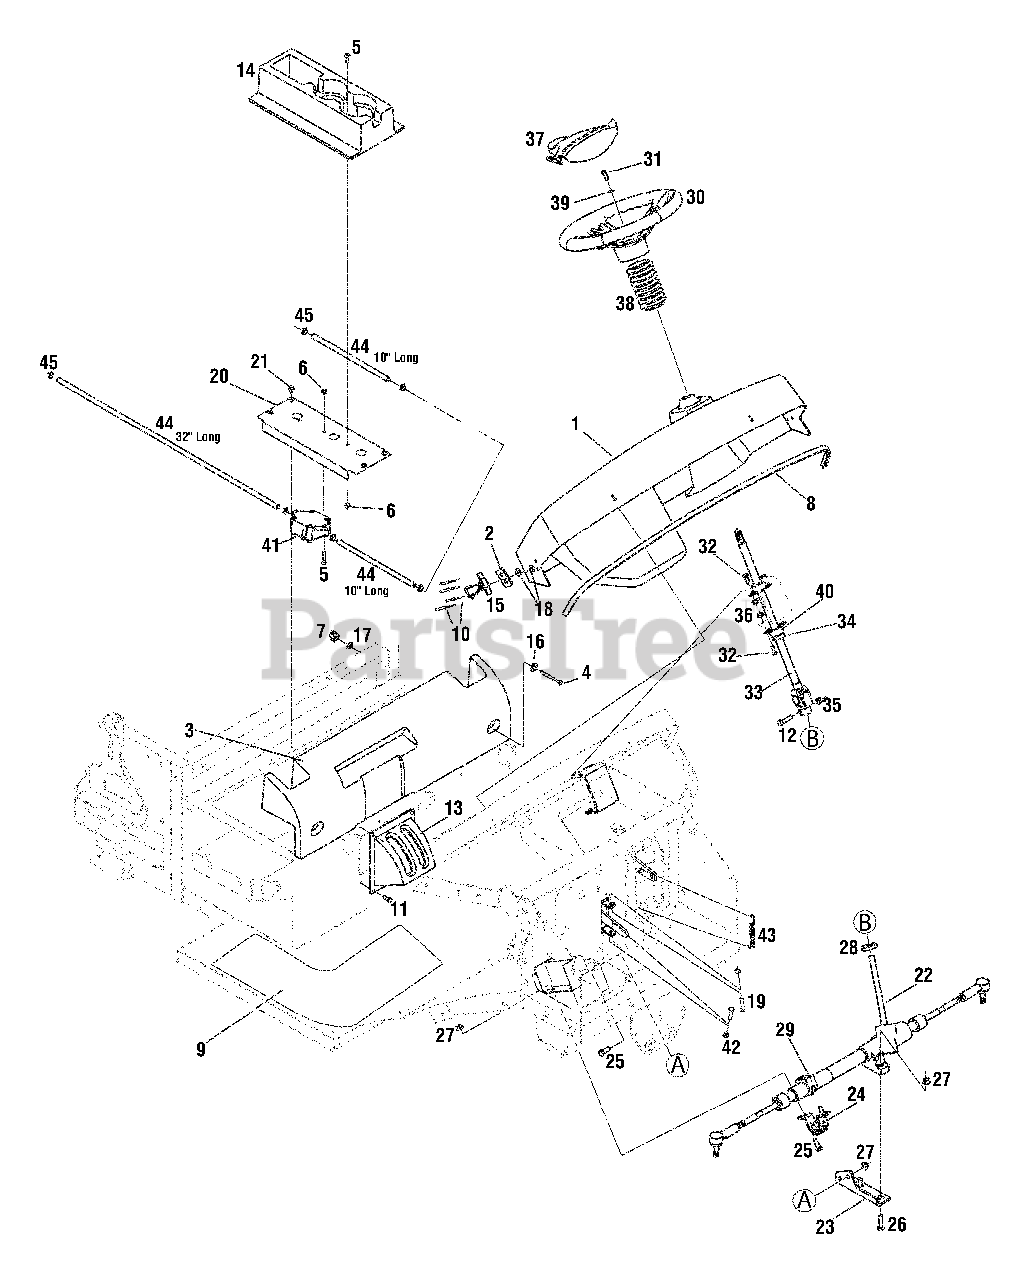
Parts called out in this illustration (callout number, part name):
1	Dash Panel
2	Hood Mounting Plate
3	Panel Cover
4	Hex Screw, 1/4-20 x 2.75
5	Hex Screw, 1/4-20 x.75, Gr5
6	Hex Lock Nut, Nylon, 1/4-20
7	Wing Nut, 1/4-20
8	Trim, Bulb Seal, 1/4
9	Foot Pad, Abrasive
10	Rivet, Pop,.187
11	Rivet, Pop,.188
12	Hex Screw, 3/8-16, 1.75, GR5
13	Panel, Shift Cover
14	Console, Cup Holder
15	Handle, Latch
16	Flat Washer, 349 x.875 x.04
17	Washer, Flat,.28 x.74 x.063
18	Washer, Flat,.194 x.62 x.063
19	Hex Screw, 5/16-18 x 1.25
22	Gear Assembly, Steering
25	Hex Screw, 3/8-16, 1.00, Gr8
26	Hex Screw, 3/8-16, 1.50, Gr8
27	Nut, Flange Lock, 3/8-16
28	Grommet, Steering Shaft
29	Bushing, Rubber
30	Wheel, Steering
31	Hex Screw, 5/16-18,.75, Gr5, Patch
32	Hex Screw, 5/16-18, .75, Gr5
33	Shaft, Steering, 5/8 Spline
34	Collar, .75
35	Nut, Hex Lock Nylon, 3/8-16
36	Nut, Flange Lock, 5/16-18
37	Cover, Steering Wheel
38	Bellow, Steering, 4.75 Lg
39	Washer, Flat,.344 x.688 x.065
40	Bearing, Flange,.75 ID, Self-Aligning
42	Hex Nut, 5/16-18
43	Extension Spring
44	Fuel Line Hose
45	Clamp, Hose
